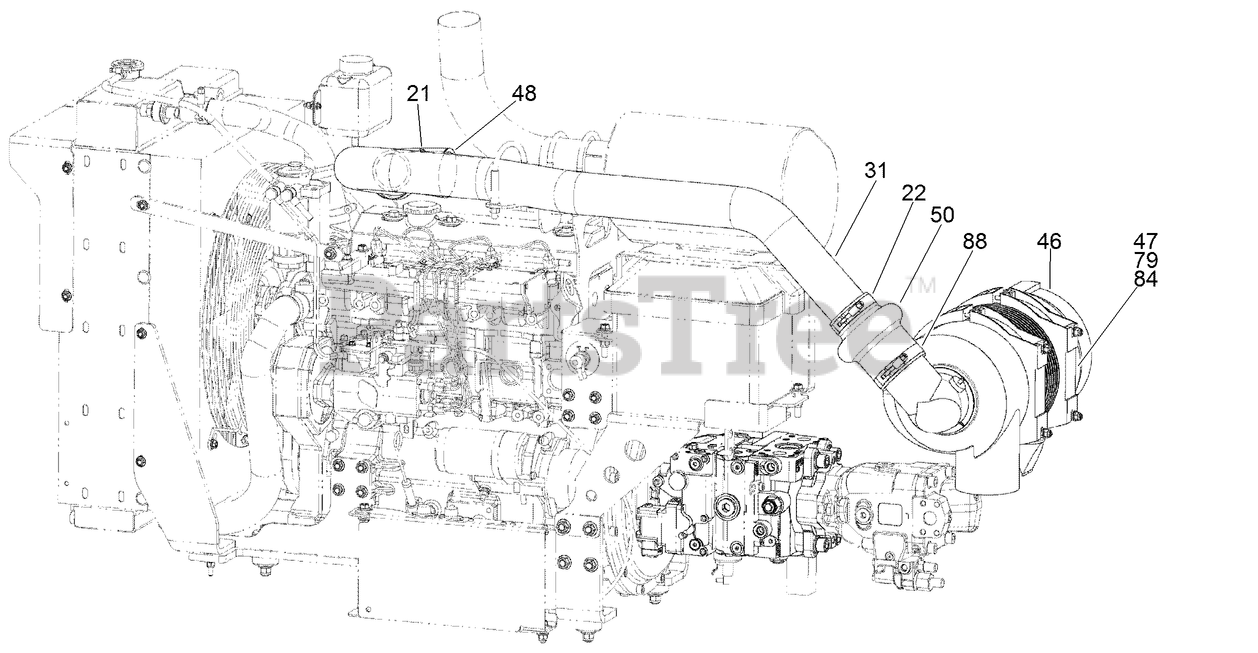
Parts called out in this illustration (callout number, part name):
21	CLAMP - Constant Torque
22	CLAMP - TBolt, Spring Load Min 3.38 Max 3.69
31	TUBE - Air Intake
46	ASM-Air Cleaner
47	MOUNT-Air Cleaner
48	RUBBER HOSE REDUCER
50	REDUCER-HOSE
79	NUT-TORQUE, PREVAILING
84	SCREW-HHF
88	CLAMP - TBolt, Min 95.3 Max 103.2
